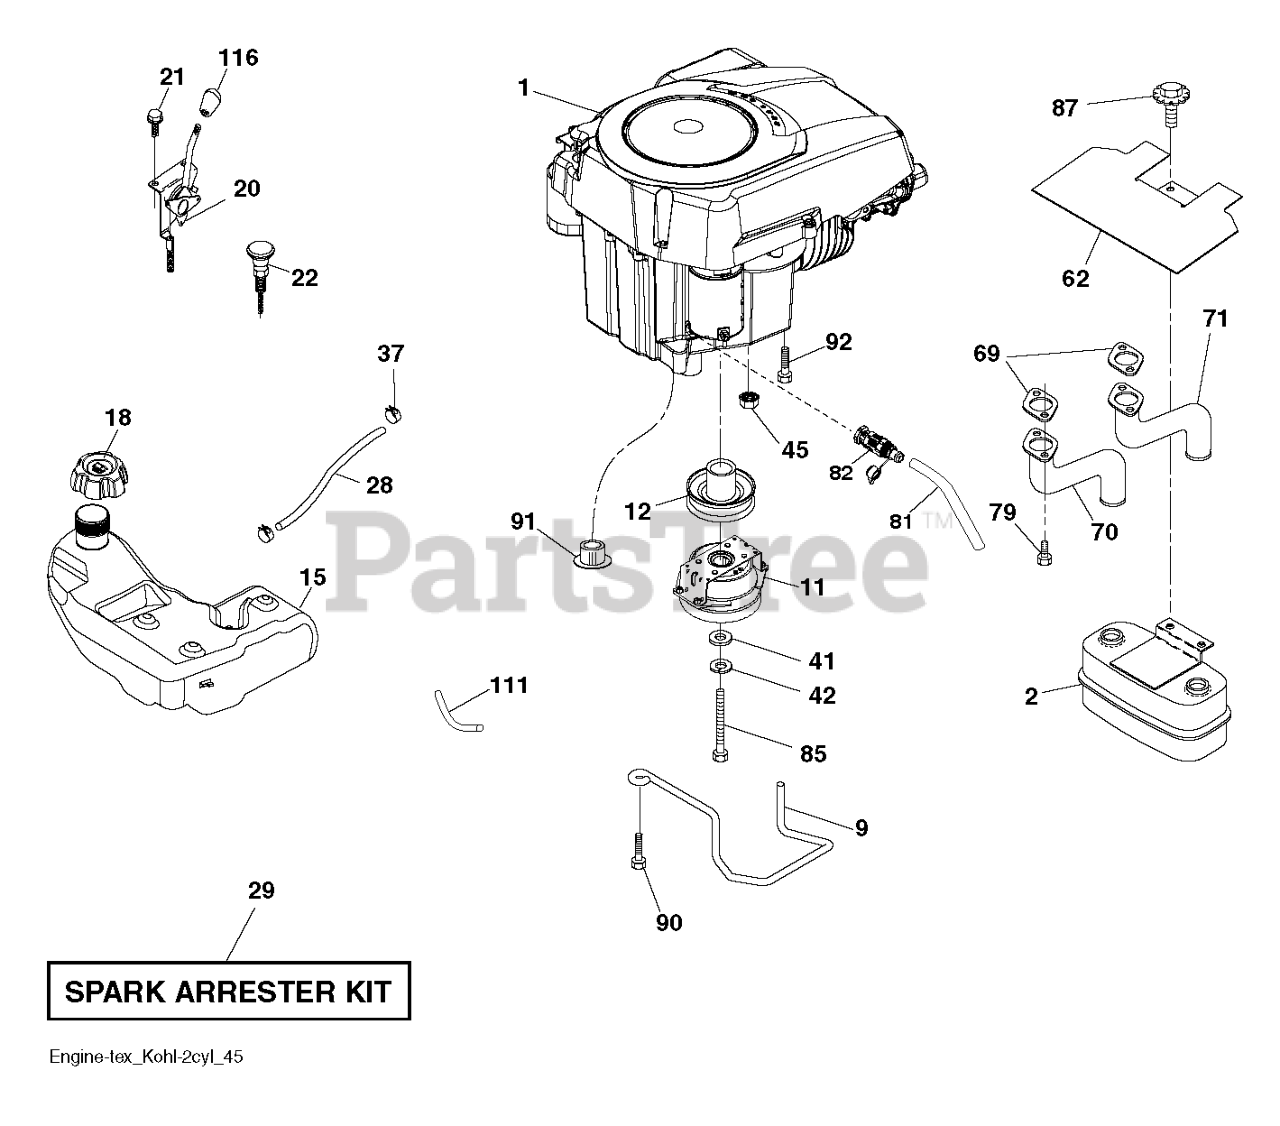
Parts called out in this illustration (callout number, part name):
2	MUFFLER.ASM.TWN.EXTNDED.DFLCTR
9	KEEPER BELT ENGINE
11	CLUTCH.OGURA.4.4PD.GT1.5-EH13V
12	PULLEY.ENGINE.TUFFTORQ
15	TANK.ASM.FUEL.3GA.CARB
18	CAP ASSY FUEL 3" GRAY
20	CONTROL.THROTTLE.PRO.KOHLER
21	SCREW.#10 X 0.750.BOS
22	CONTROL.CHOKE.ERGO.PUSH-IN.BLA
28	LINE.FUEL.64"REAR.EMIS
29	KIT.SPARK ARRESTOR 794945 B&S
37	HOSE CLAMP
42	LOCKWASHER
45	NUT
62	SHIELD.HEAT.MUFFLER
69	GASKET.EXHAUST.KOHL.CV18-CV26
70	PIPE.EXHAUST.LH.CV18/20
71	PIPE.EXHAUST.RH.CV18/20
79	SCREW.SOCKET HD.5/16-1
81	TUBE, DRAIN OIL ASM.
82	VALUE.OIL.DRAIN
85	CLUTCH BOLT7/16-20X3.5 GR524HR
87	BOLT.5/16-18UNCX3/4 W/SEMS.BLK
90	SCREW 3/8-16X1
91	BUSHING.1.375OD
92	SCREW 3/8-16X1
111	RP PURGE LINE
116	KNOB - SHIFT
